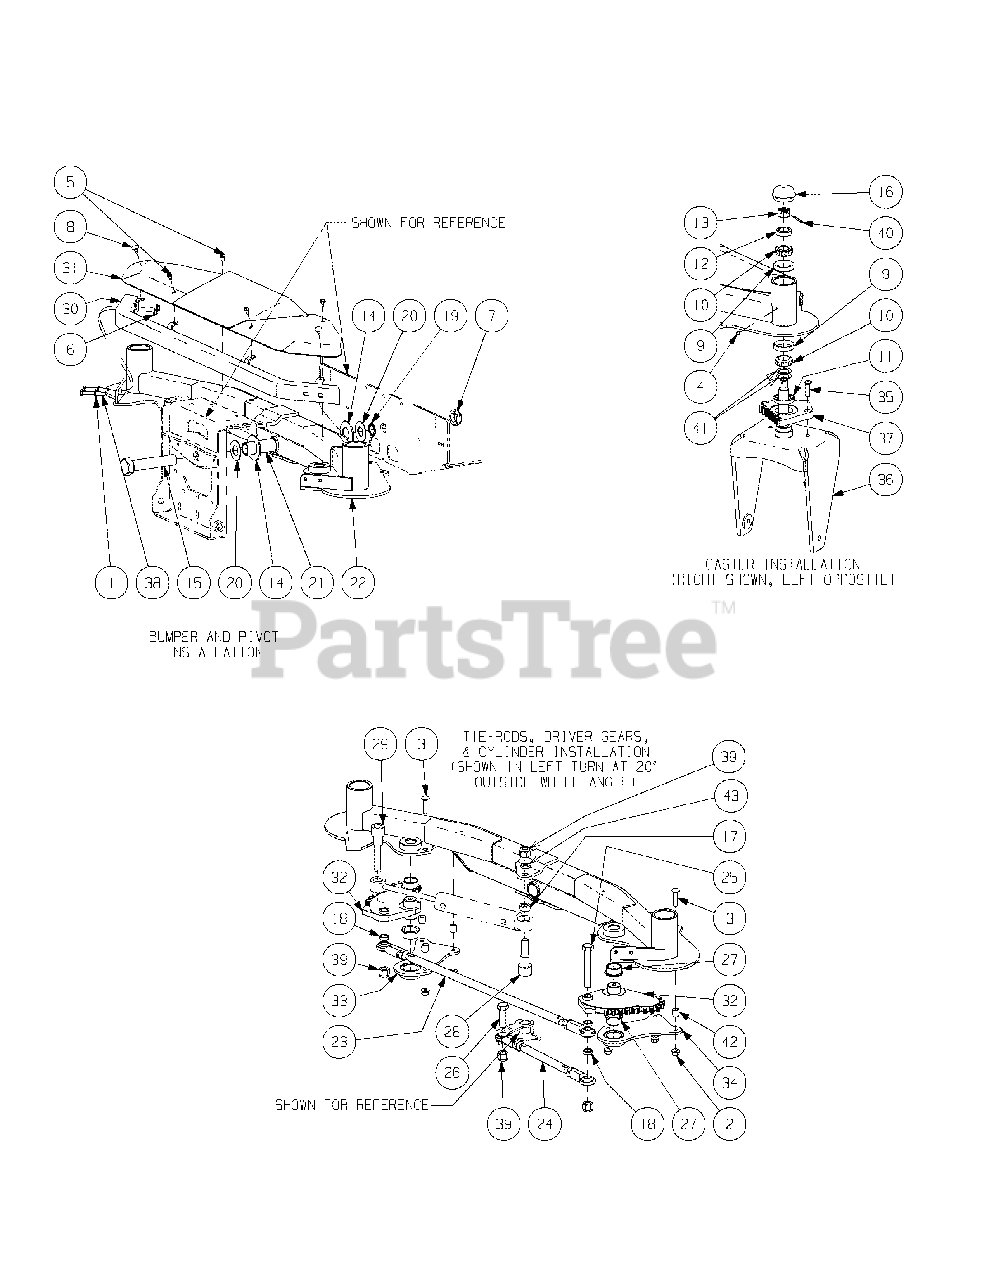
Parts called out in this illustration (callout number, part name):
1	Flat Washer, 5/16
2	Flange Lock Hex Nut, 3/8-16
3	Carriage Bolt, 3/81-6 x 1-1/2
4	Grease Fitting, 1/4-28 x 3/16
5	Screw, TT, 1/4-20, 0.5, Hex Index Washer
6	Nut, Lock, HexFlange, 5/16-18
7	Nut, 1.0-14, Flange TopLock
8	Rubber Bumper, .62 OD x .22 THK
9	Cup Bearing
10	Bearing Cone
11	Seal
12	Ring Seal
13	Slotted Nut, 3/4-16
14	Bell Washer, 1.25 ID x 2.5 x .157
15	Hex Cap Screw, 1-14 x 5.0
16	Grease Cap, 1.986 OD
17	Spacer, .630 ID x 1.06 OD x .440
18	Spacer, .635 ID x .28 LG
19	Retainer Extension, Self Locking
20	Flat Washer, 1.00 ID
21	Spacer, 1.005 ID x 1.25 OD x 3.6
22	Axle Assembly
23	Tie Rod Assembly, 1/2-20 x 15.95 LG
24	Tie Rod Assembly, 5/8-18 x 14 LG
25	HHCS, 5/8-11 x 4.00
26	HHCS, 5/8-11 x 2.00
27	Flange Bearing, 1.253 x 1.749 x .740
28	Shoulder Bolt, .875 x 1.030 x 1.75
29	Shoulder Bolt, .875 x 1.030 x 2.88
30	Front Bumper Assembly
31	Axle Cover Assembly
32	Driver Gear
33	Steering Support Bracket Assembly, LH
34	Steering Support Bracket Assembly, RH
35	FHCS, 3/8-16 x 1.50
37	Steering Gear
38	HHCS, 5/16-18 x 2-1/4
39	Nut, 5/8-11m Hex Nylon Lock
40	Cotter Pin, 5/32, 1.25
41	Washer, 1.00 x 1.50 x .03, SS
42	Spacer, .407 x .625 x .675 LG
43	Washer, 1 1/2 x 5/8 x .055
